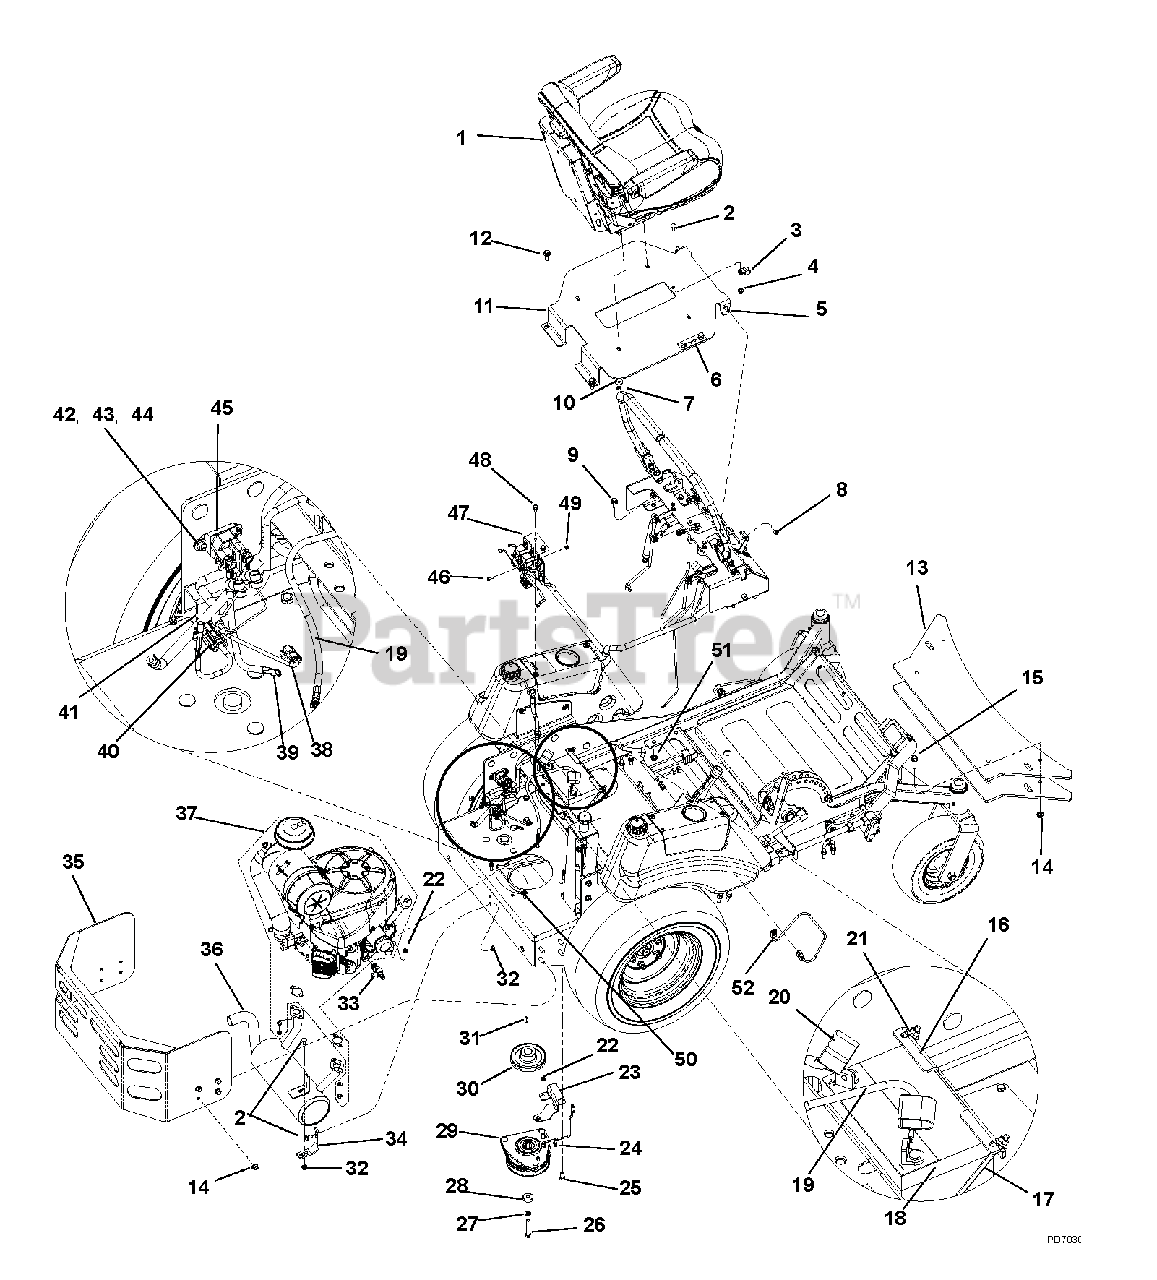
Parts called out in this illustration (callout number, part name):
1	SEAT, FULL SUSPENSION, NO LOGO
2	BOLT, M8X1.25X20 CRG 8.8 Y
3	P-CLIP, .750 INSULATED
4	LOCKNUT, M8X1.25 NYLOC FLG 10Y
5	BOLT, 1/2X1.06X3/8-16 SLD 5 Y
6	LABEL - PARK BRAKE DIRECTION
7	LOCKNUT, 5/16-18 NYLOC Y
8	NUT, 3/8 LOCK
9	SCREW,HEX,FL,JDS123,M10X1.5X25
10	WASHER, .344X1.00X.134 FLAT Y
11	PLATE, SEAT
12	SCREW,HEX,FL,JDS123,M10X1.5X30
13	PLATE, WEIGHT BLK
14	LOCKNUT,FL,ISO7044,M10X1.5-10-
15	SCREW,HEX,FL,JDS121,M10X1.5X40
16	HOLDER, BATTERY
17	J BOLT
18	BATTERY, 12V-U1-CCA400MIN
19	CABLE, BATTERY - 20" GROUND
20	CABLE, BATTERY POSITIVE
21	NUT-1/4" FLANGE PREVAILING TOR
22	LOCKNUT, 5/16-18 CROWN Y
23	PLATE, CLUTCH DOG
24	CABLE TIE, .31 X 14.6 - BLACK
25	BOLT, 7/16-14X.750 HEX 5 Y
26	BOLT, 7/16-20X2.75 HEX 5 Y
27	WASHER, .438 MED SPRG LOCK Y
28	SPACER, .468 X 1.38 X .375 Y
29	CLUTCH ASSY, OGURA# GT1A-HU02
30	PULLEY, V-BELT 4.78PD X 1.000
31	KEY, .250 X .250 X .995 TPR
32	LOCKNUT,M8X1.25,FLANGED ZN
33	FITTING, OIL DRAIN #
34	BRACKET, MUFFLER
35	BUMPER, REAR GDKW
36	MUFFLER, MINI-Z
37	ENGINE, KAWASAKI 23HP FH680V
38	HARNESS. SEAT RELAY
39	CABLE, 12" STARTER
40	HARNESS, PIGTAIL
41	FUSIBLE LINK, 10"
42	BOLT, 1/4-20X.750 HEX 5 Y
43	LOCKNUT, 1/4-20 CENTER Y
44	MANUAL,OWNERS RAPID XZ TRACTOR
45	SOLENOID
46	SCREW,FL,JDS123,M6X1X16-10.9-Z
47	BRACKET, ELECTRIC MOUNTING
48	SCREW,HEX,FL,JDS123,M8X1.25X16
49	LOCKNUT,FL,ISO7043,M6X1.00-10-
50	BOLT, 5/16-18X1.75 HEX 5 Y
51	LOCKNUT, M10X1.50 WHIZ GR10 Y
52	HARNESS, WIRING
